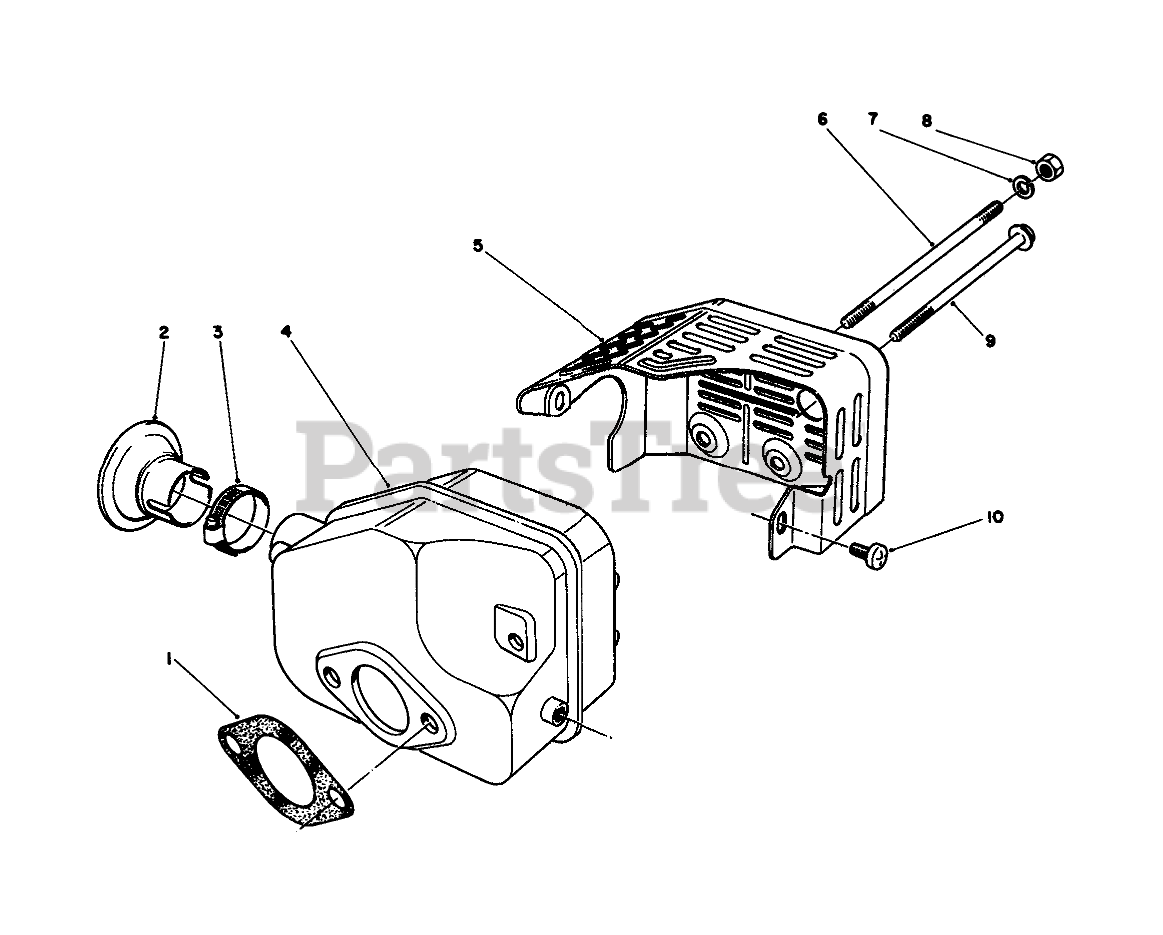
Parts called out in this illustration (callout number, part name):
1	GASKET
2	Arrestor-Spark
3	Clamp-Hose
4	Muffler
5	COVER-MUFFLER
7	WASHER-LOCK
10	SCREW
